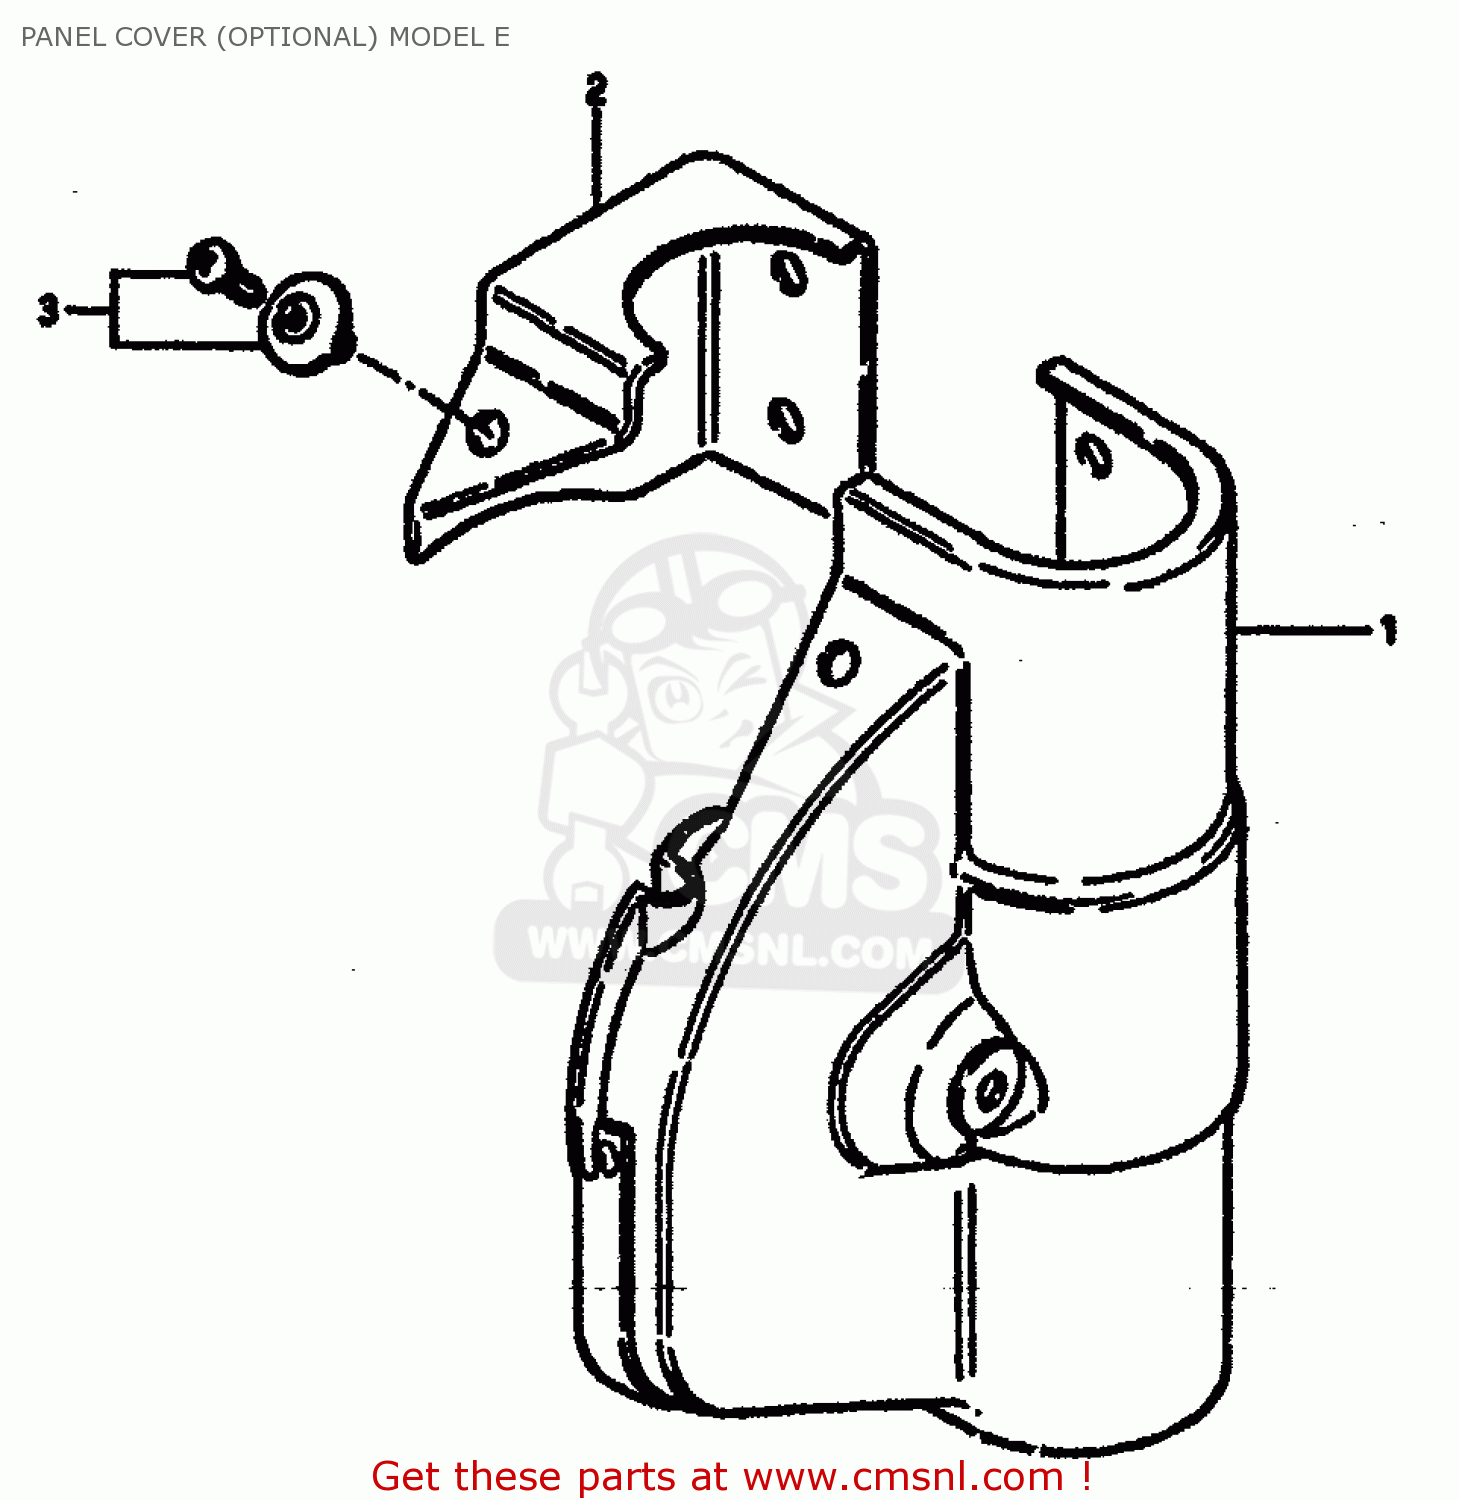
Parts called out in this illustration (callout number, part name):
1	COVER,FRONT HUB PANEL
2	CAP
3	CLIP(BLACK)
